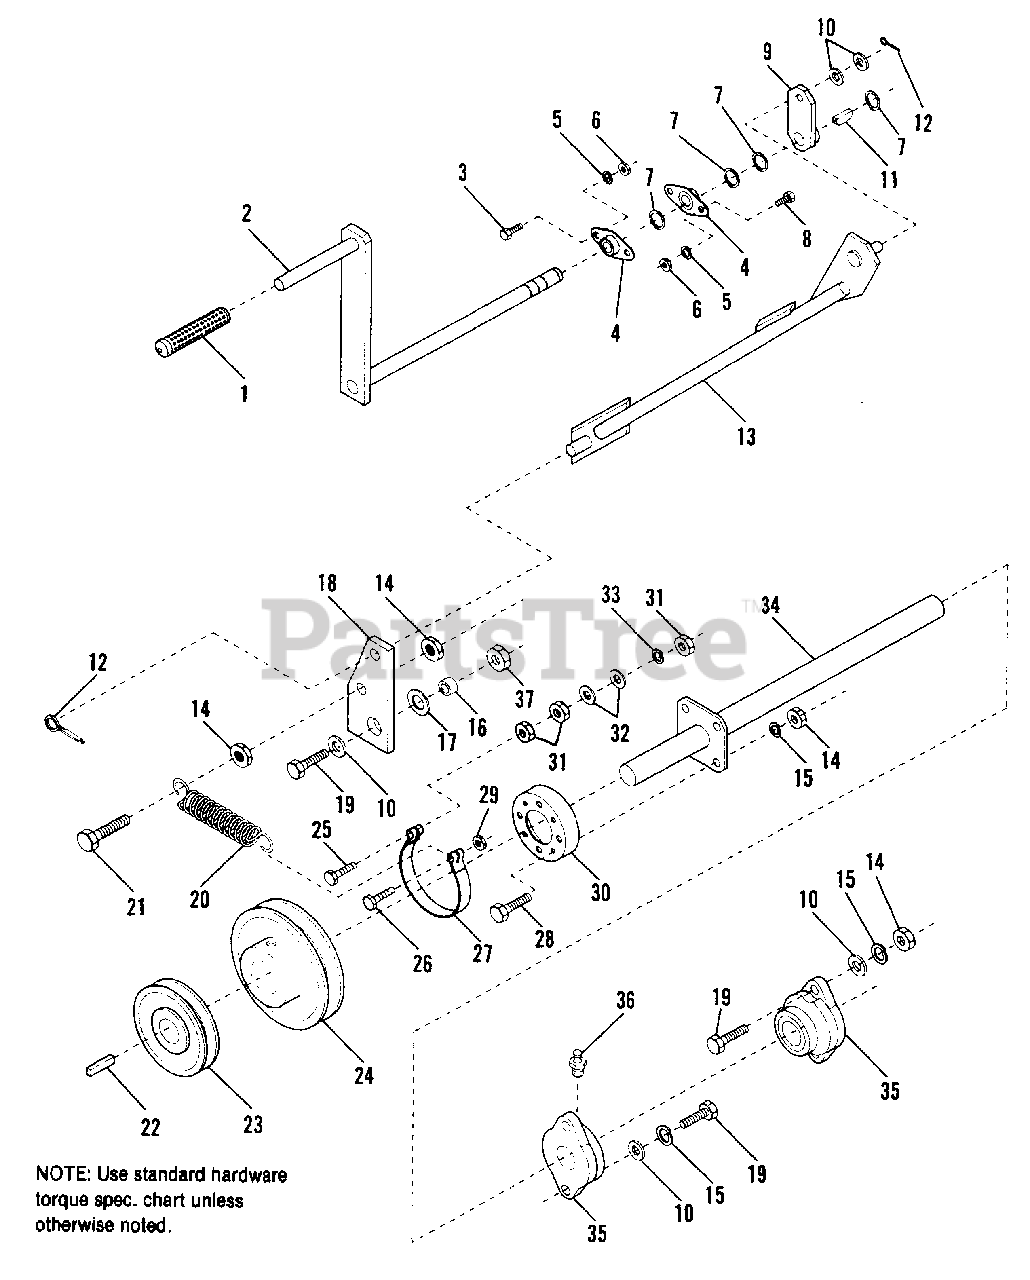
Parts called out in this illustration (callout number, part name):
2	PTO HANDLE ASSY.
3	CAPSCREW, Hex, 1/4-20 x 1/2
4	BEARING, Flanged
5	LOCKWASHER, Spring, 1/4
6	NUT, Hex, 1/4-20
7	RING, Retaining, External, 5/8
8	CAPSCREW, Hex, 1/4-20 x 3/4
10	WASHER, Plain
11	KEY, Woodruff, 3/16 x 3/4
14	NUT, Hex, 5/16-18
15	LOCKWASHER, Spring, 5/16
17	WASHER, Plain
18	ARM, Brake
19	CAPSCREW, Hex, 5/16-18 x 1-1/4
20	SPRING, Tension
21	CAPSCREW, Hex, 5/16-18 x 1-1/2
22	KEY, Square, 1/4 x 2-1/4
23	V-PULLEY, PTO
24	V-PULLEY, PTO
25	CAPSCREW, Hex, 3/8-16 x 2-1/2
26	CAPSCREW, Hex, 3/8-16 x 1-1/2
27	BAND, Brake
28	CAPSCREW, Hex, 5/16-18 x 3/4
29	LOCKNUT, Hex, 3/8-16
30	DRUM, Brake
31	NUT, Hex 3/8-16
32	WASHER, Plain
33	LOCKWASHER, Spring, 3/8
34	JACKSHAFT ASSY.
35	BEARING, Collared
36	FITTING, Grease
37	LOCKNUT, Hex Flanged, 5/16-18
